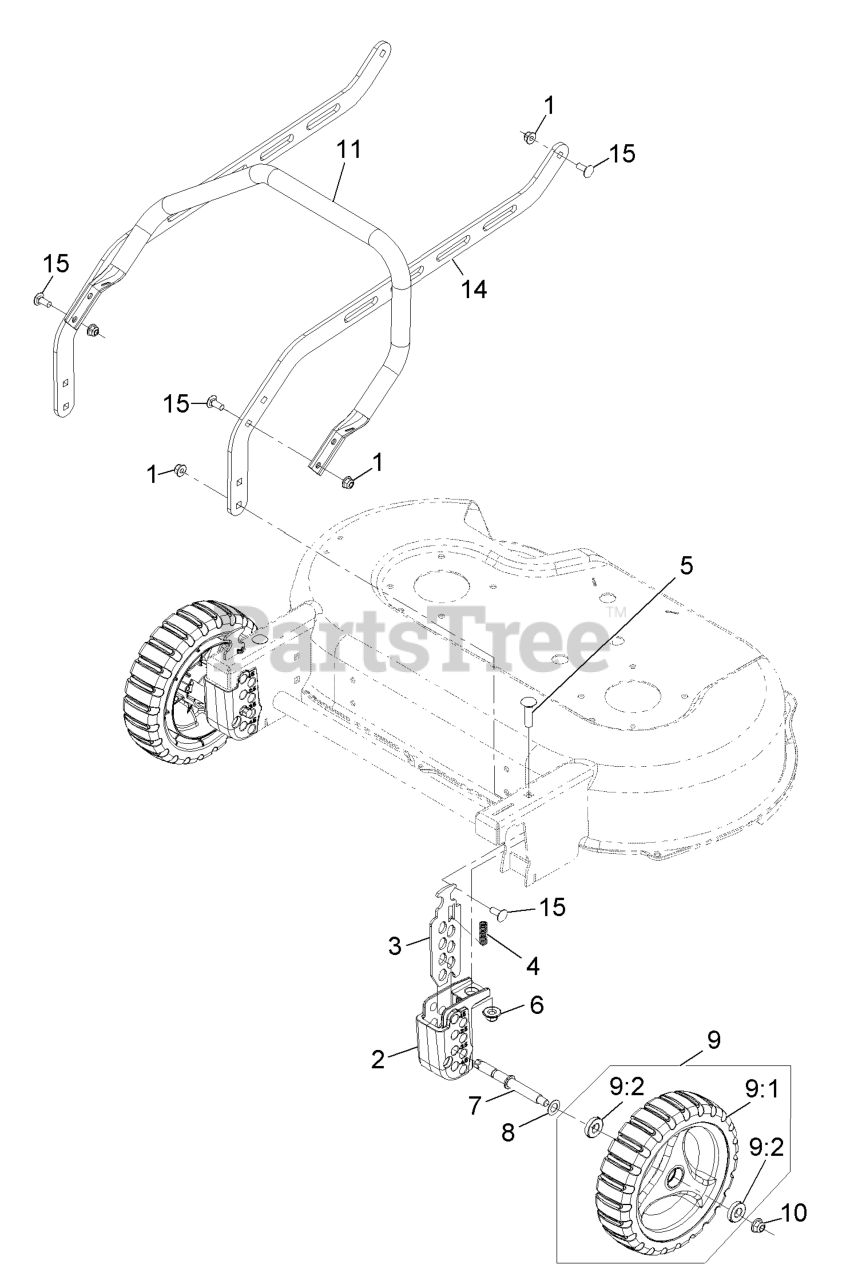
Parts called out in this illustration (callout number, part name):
1	NUT-HF, NI
2	BLOCK-FRONT QUADRANT
3	PLATE, FRONT HEIGHT
4	SPRING-COMPRESSION
5	SCREW-CARR
6	Nut-Nyloc 3/8-16 Flg
7	AXLE-WHEEL
8	WASHER-PLAIN
9:2	BEARING-BALL
10	NUT-HF, NI
11	GUARD-ENGINE
15	SCREW-CARR
